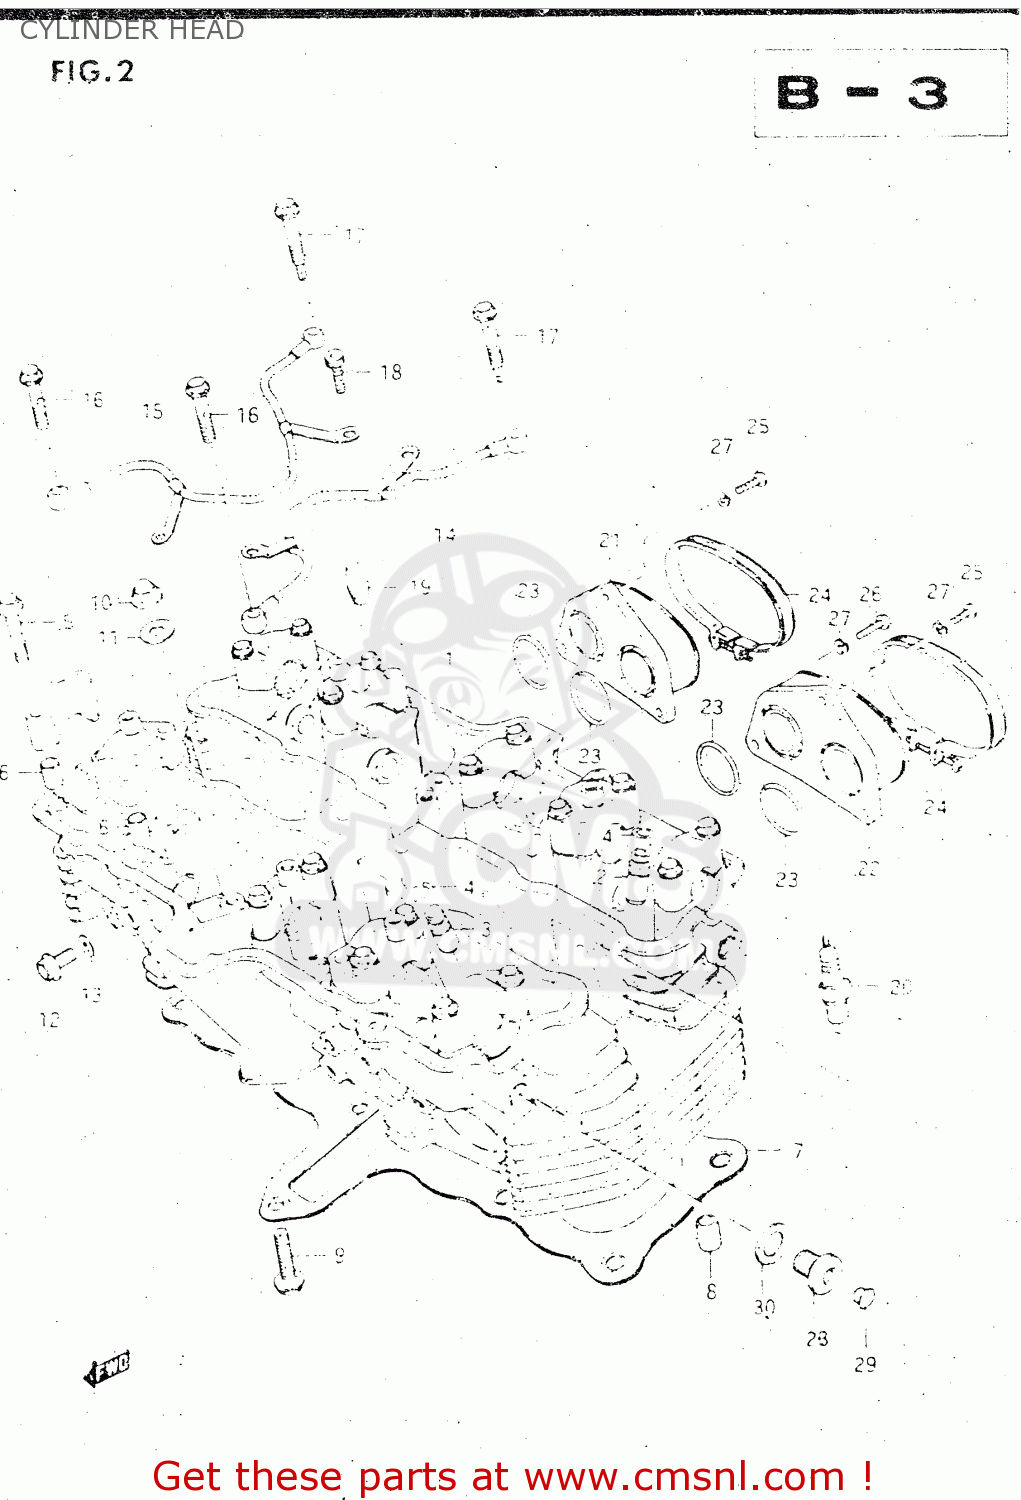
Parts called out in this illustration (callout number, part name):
1	HEAD ASSEMBLY,CYLINDER
2	GUIDE,VALVE
3	GUIDE,VALVE
4	RING,SNAP
5	BOLT(6X39)
6	PIN(6.2X8X11)
7	GASKET,CYLINDER HEAD (NAS)
8	PIN
9	BOLT
10	NUT
11	GASKET(8.5X20X2.3) (NAS)
12	BOLT 6X12
13	GASKET(6.2X13X1.2) (NAS)
14	PIPE,OIL CYLINDER HEAD
15	PIPE,OIL CYLINDER HEAD
16	UNION
17	BOLT,UNION
18	BOLT, 6X16
19	PAD,CYLINDER
20	PLUG,SPARK(DR8ES)
21	PIPE,INTAKE,R
22	PIPE,INTAKE,L
23	O-RING (D:2.4 ID:29.7)
24	CLAMP
25	SCREW
26	SCREW
27	WASHER,LOCK
28	PLUG
29	CAP(OD:12)
30	GASKET(14X19.2X2) (NAS)
